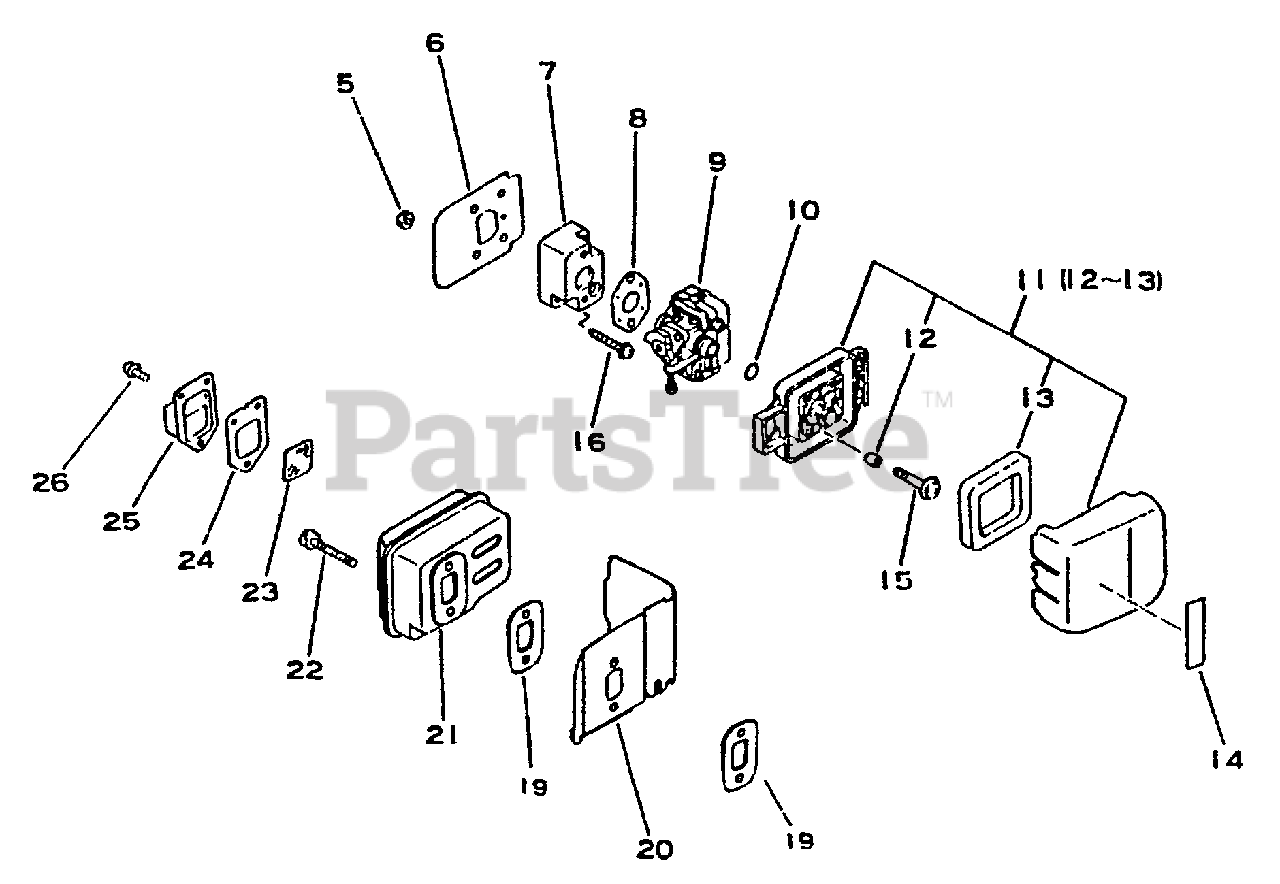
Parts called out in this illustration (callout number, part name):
6	SHIELD, INTAKE
7	INSULATOR, INTAKE
8	GASKET, INTAKE
9	CARBURETOR WYL-7
10	O-RING - 15
11	AIR CLEANER ASSY
12	SLEEVE
13	FILTER, AIR
15	SCREW - 5X64
16	SCREW - 5X22
19	GASKET, EXHAUST
20	COVER, EXHAUST
21	MUFFLER
22	SCREW - 5X55
23	SCREEN, SPARK ARRESTOR
24	GASKET, EXHAUST
25	GUIDE, EXHAUST
26	SCREW - 4X10
